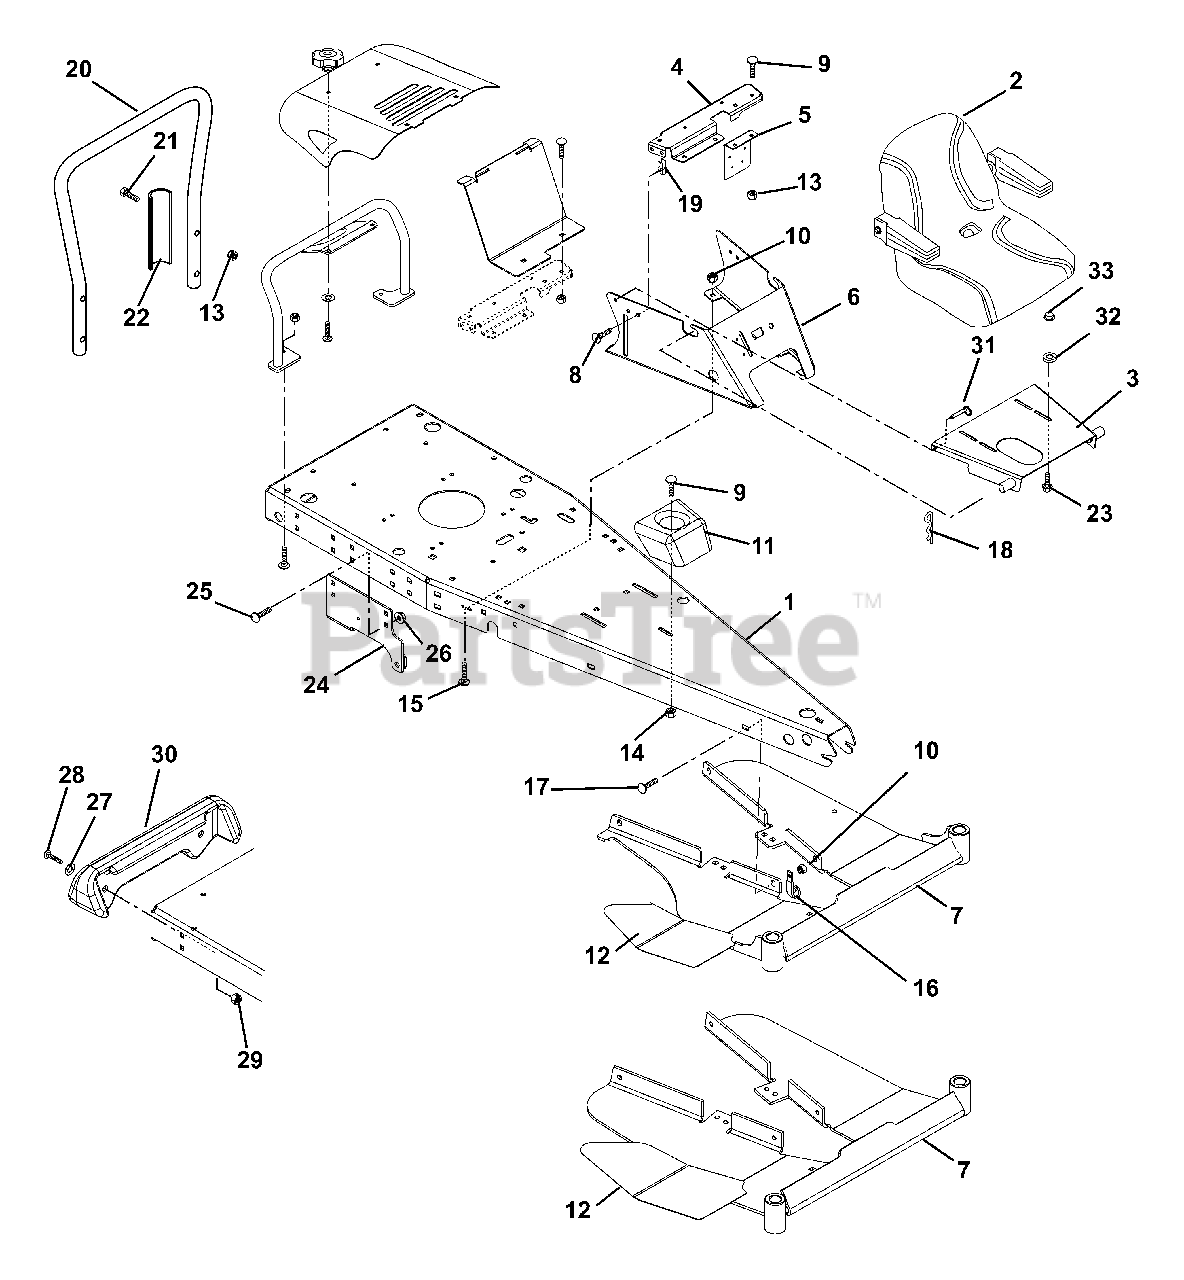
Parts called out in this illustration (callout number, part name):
1	FRAME,RER/SPORT-ZOOM
2	SEAT, TS2500 MICHIGAN W/ARM.
3	WLDM'T, SEAT PLATE
4	REINFORCEMENT, SEAT SUPPORT
5	PANEL-SOLENOID MOUNTING
6	SEAT SUPPORT
7	REST, RER/SZ FOOT
7	WLDMT-FOOTREST RER/MINI-Z-
8	BLT-SERHFWH .25-20X.75 YWZC
9	BLT-RDHDSQNK .31-18X.75 G5BZ
10	NUT-LK-TOP-FLG .38-16 BLKZC
11	CUP HOLDER RER
12	GRIP, LEFT FOOT REST
12	GRIP, RER FOOTREST (LH)
12	GRIP, RH FOOT REST
13	GRIP, RER FOOTREST (RH)
14	@NUT-SPNLK-FLG .312-18 YWZC
14	NUT-LK-TOP-FLG .31-18 BLKZC
15	BLT-RDHDSQNK .38-16X.75 G5BZ
16	J-CLAMP
17	BLT-RDHDSQNK .38-16X1.00 G5BZ
18	PIN-HAIR-EXT .12X.31X2.37 YWZC
19	NUT-RTNR .25-20X.56
20	TUBE
21	@BLT-HEX .31-18X1.50 GR5 YWZC
22	BRACE
23	BLT-SERHFWH .31-18 X 1 YWZC
24	BRKT, TRANS (RH-WLDMNT)
24	BRKT, TRANS (LH-WLDMNT)
25	BLT-RDHDSQNK .38-16X.75 G5BZ
26	NUT-LK-TOP-FLG .38-16 BLKZC
27	@WSHR-FL-STL.438X1.00X.083 YWZ
28	@BLT-HEX .38-16X1.75 GR5 YWZC
29	NUT-LK-TOP-FLG .38-16 BLKZC
30	WEIGHT, SPORT-Z
31	PIN-DET W/RING .25X1.00
32	SPACER, .344X1.00X.410
33	NUT-PUSH .312
